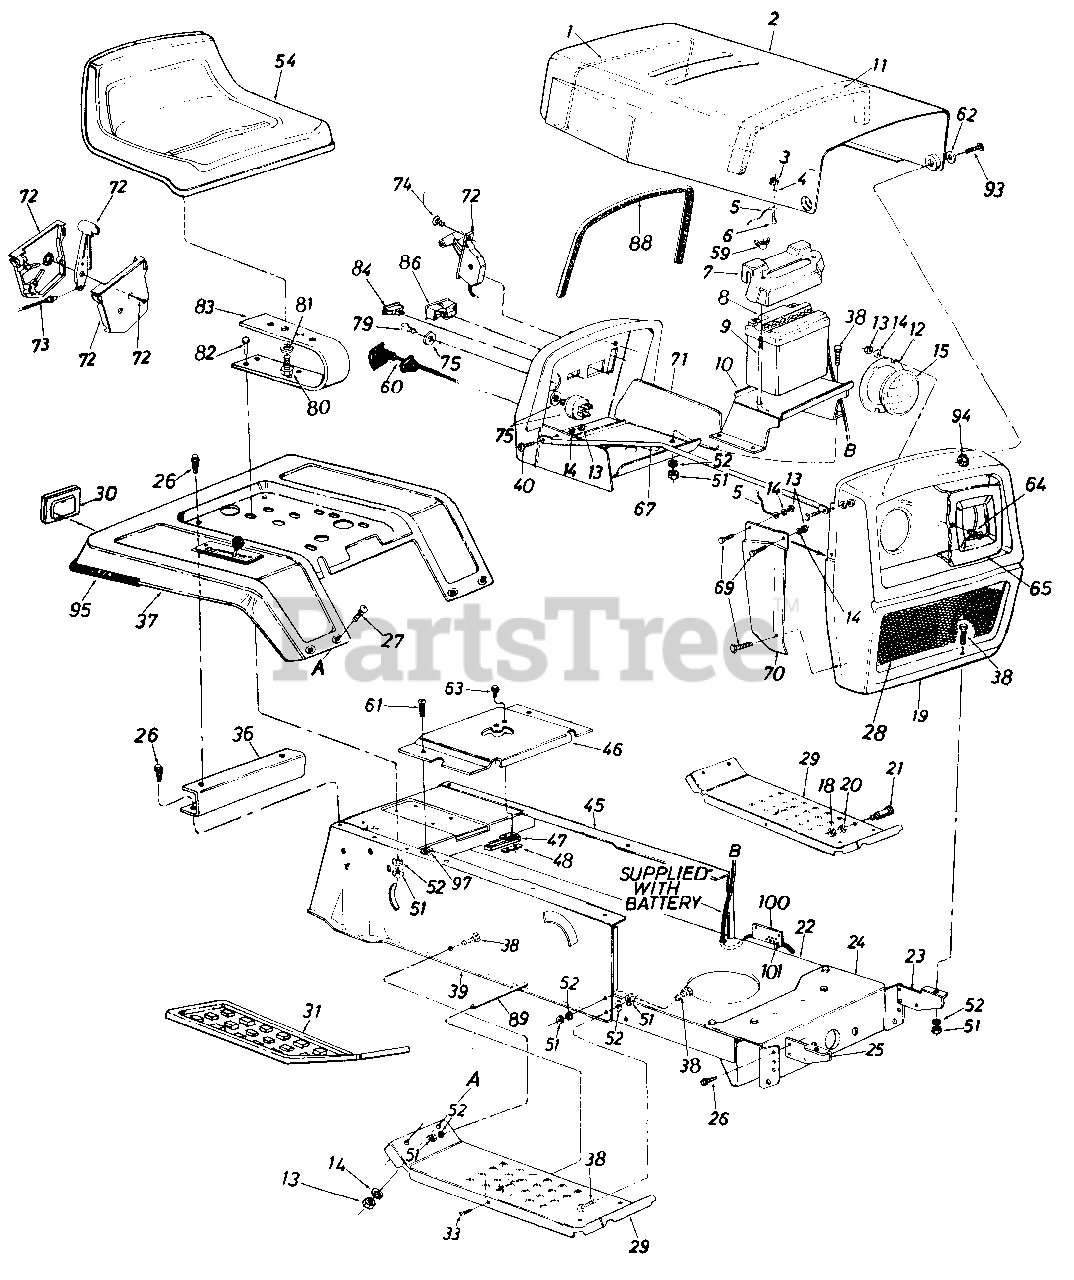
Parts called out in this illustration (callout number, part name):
1	Hood Spring
4	Push Mount Tie
5	Hood Stop 7" Lg.
6	Truss Hd. Scr. #10-24 x '/2"
7	Battery Cover
8	12 Volt Battery
9	Battery Hold Down Rod
10	Battery Bracket
11	PVC Foam-Strip
12	Headlight Retainer
13	Hex Nut 1/4-20 Thd.
14	L-Wash. 1/4" I.D.*
15	Headlight
18	Hex Nut 3/8-16 Thd.
21	Shld. Bolt .50" Dia. x .84
22	Lower Frame
23	Grille Mount Brkt.-L.H.
24	Front Pivot Brkt.
25	Grille Mount Brkt.-R.H.
26	Hex Wash. Hd. AB-Tap Scr. 5/16 x .75" Lg.
27	Carriage Bolt 1/4-20 x 2.00" Lg.
28	Grille Insert
29	Running Board
30	Reflector
31	Foot Pad
33	Truss Mach. Scr. 5/16-18 x .75" Lg.
36	Fender Mount Brace
37	Fender
38	Hex Bolt 5/16-18 x .75" Lg.
39	R.H. Side Frame
40	Hex Bolt 1/4-20 x .62" Lg.
45	L.H. Side Frame
46	Shift Cover
47	Reverse Safety Switch
48	Insulator Nut Plate
51	Hex Nut 5/16-18 Thd.
52	L-Wash. 5/16" I.D.
54	Seat Ass'y.
59	Wing Nut 1/4-20 Thd.-Plastic
60	Choke Control 44" Lg.
61	Truss Mach. Tap Scr. #10 x .50" Lg.
62	Washer .39" I.D. x .62" O.D.
63	Hex Wash. Hd. AB-Tap Scr. #8 x .50
64	Truss Hd. Scr. #10-24 x .38" Lg.
65	Bezel
69	Truss Hd. Scr. 1/4-20 x .75"
70	R.H.-Grille Side Panel
71	Dash Panel Ass'y.
72	Throttle Control Box Ass'y.
73	Throttle Control Wire-35"
74	Truss Mach. AB-Tap Scr. #10 x .5" Lg.
75	Ignition Switch
79	Ignition Key
80	Hex Bolt 1/2-13 x 1.00" Lg. (Grade 5)
81	L-Wash. 1/2" I.D.
82	Hex Bolt 5/16-18 x 1.00" Lg.
83	Seat Spring 5.5" High
84	Light Switch
86	Ammeter
88	Molding Strip 27" Lg.
89	Running Board Rod
93	Shld. Bolt .375 Dia. x .125
94	L-Nut 1/4-28 Thd.
95	Trim Strip 31.0" Lg.
97	Speed Nut #10Z
100	Brake Cable Bracket
101	Cable Tie
